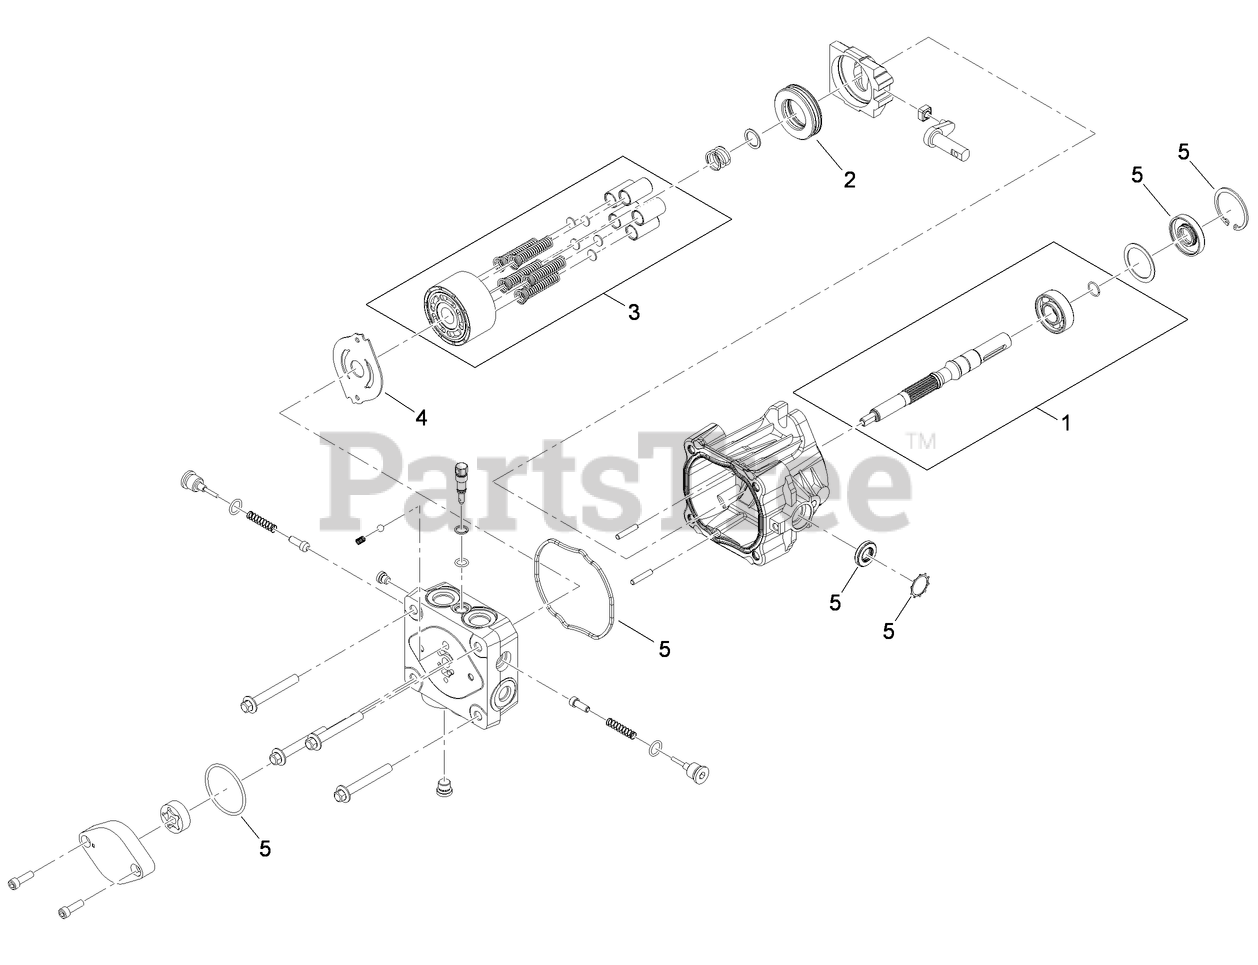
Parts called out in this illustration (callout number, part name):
1	INPUT SHAFT KIT
2	BEARING-THRUST
3	CYLINDER BLOCK KIT
4	Plate-Valve
5	SEAL OVERHAUL KIT
